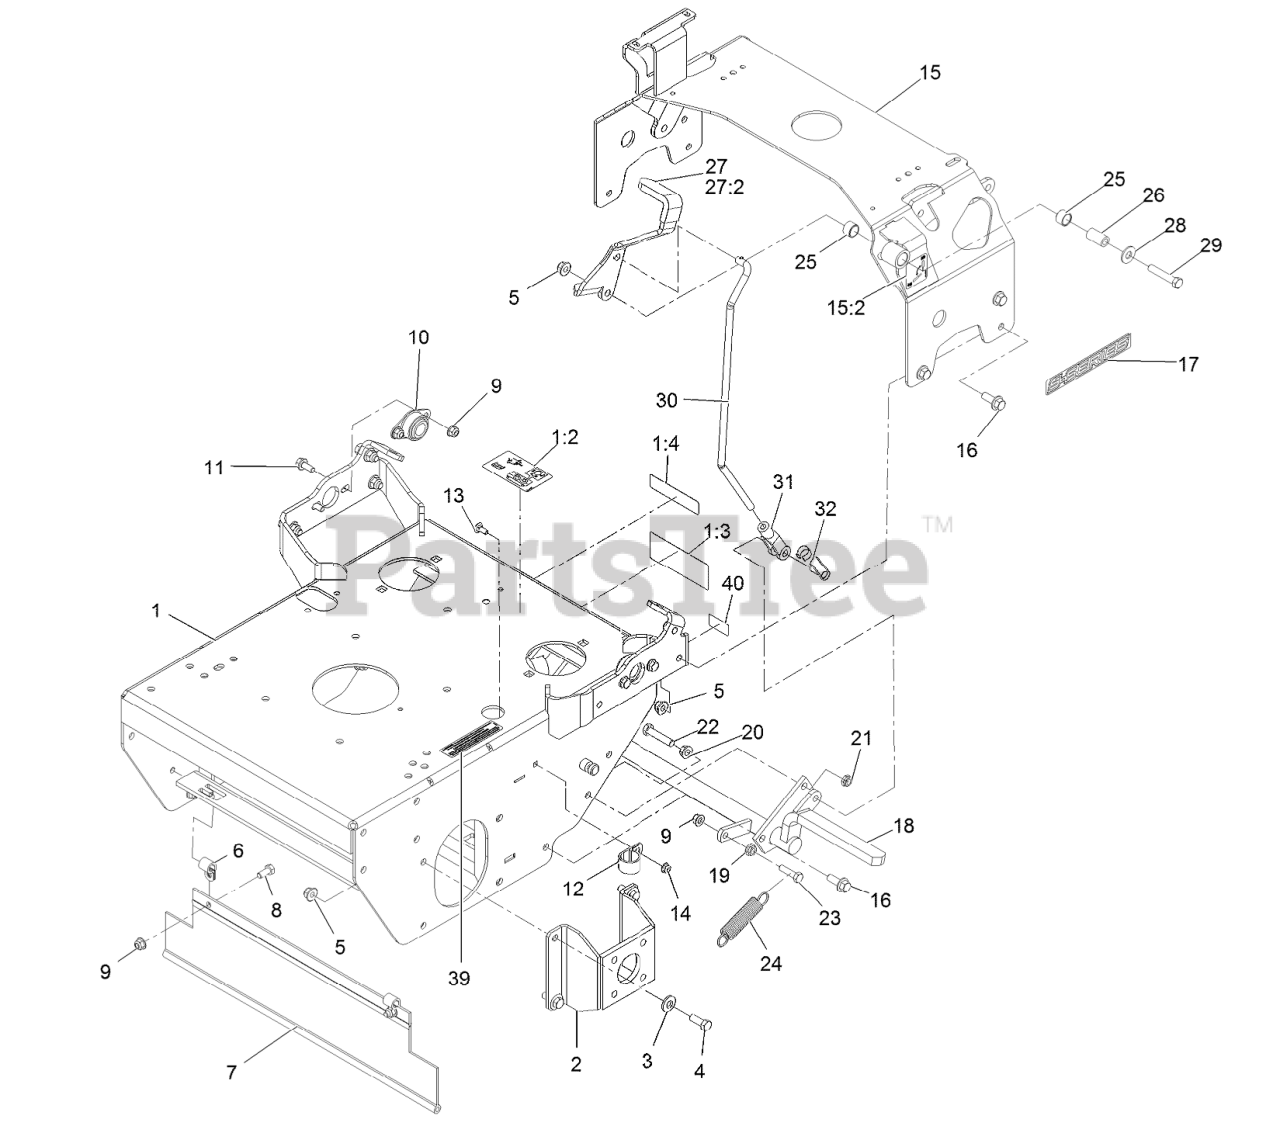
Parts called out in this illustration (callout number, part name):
1	ASM, ENGINE DECK W/ DECAL
1:2	DECAL-DRIVE RELEASE
1:3	DECAL-WARNING, SULKY
1:4	DECAL-WARNING
2	WLD,MOTOR MOUNT 48&52
3	WASHER-BELLEVILLE
4	SCREW-HH
5	NUT-HF, NI
6	CLIP-LOOM
7	SHIELD-DRAG
8	SCREW-HH
9	NUT-HF, NI
10	BEARING-FLANGE, SIDE
11	SCREW-HHF
12	CLIP-LOOM
13	SCREW-CARR
15	ASM, TANK SUPPORT W/ DECA
15:2	DECAL-PARK BRAKE, CE
16	SCREW-HHF 3/8-16 X 1
17	DECAL-S-SERIES
20	NUT-HHF, WHIZ
22	SCREW-HH
23	SCREW-HH
24	SPRING-IDLER
25	SLEEVE-BUSHING
26	BUSHING-PIVOT
27	ASM, BRAKE LEVER W/ GRIP
27:2	GRIP-LEVER
28	WASHER-FLAT
29	SCREW-HH
30	LINKAGE, BRAKE
31	YOKE-LINKAGE, BRAKE
32	PIN-SPRING, CLEVIS
39	DECAL-ARRESTOR, SPARK
40	Decal-Patent Ttco.Com
